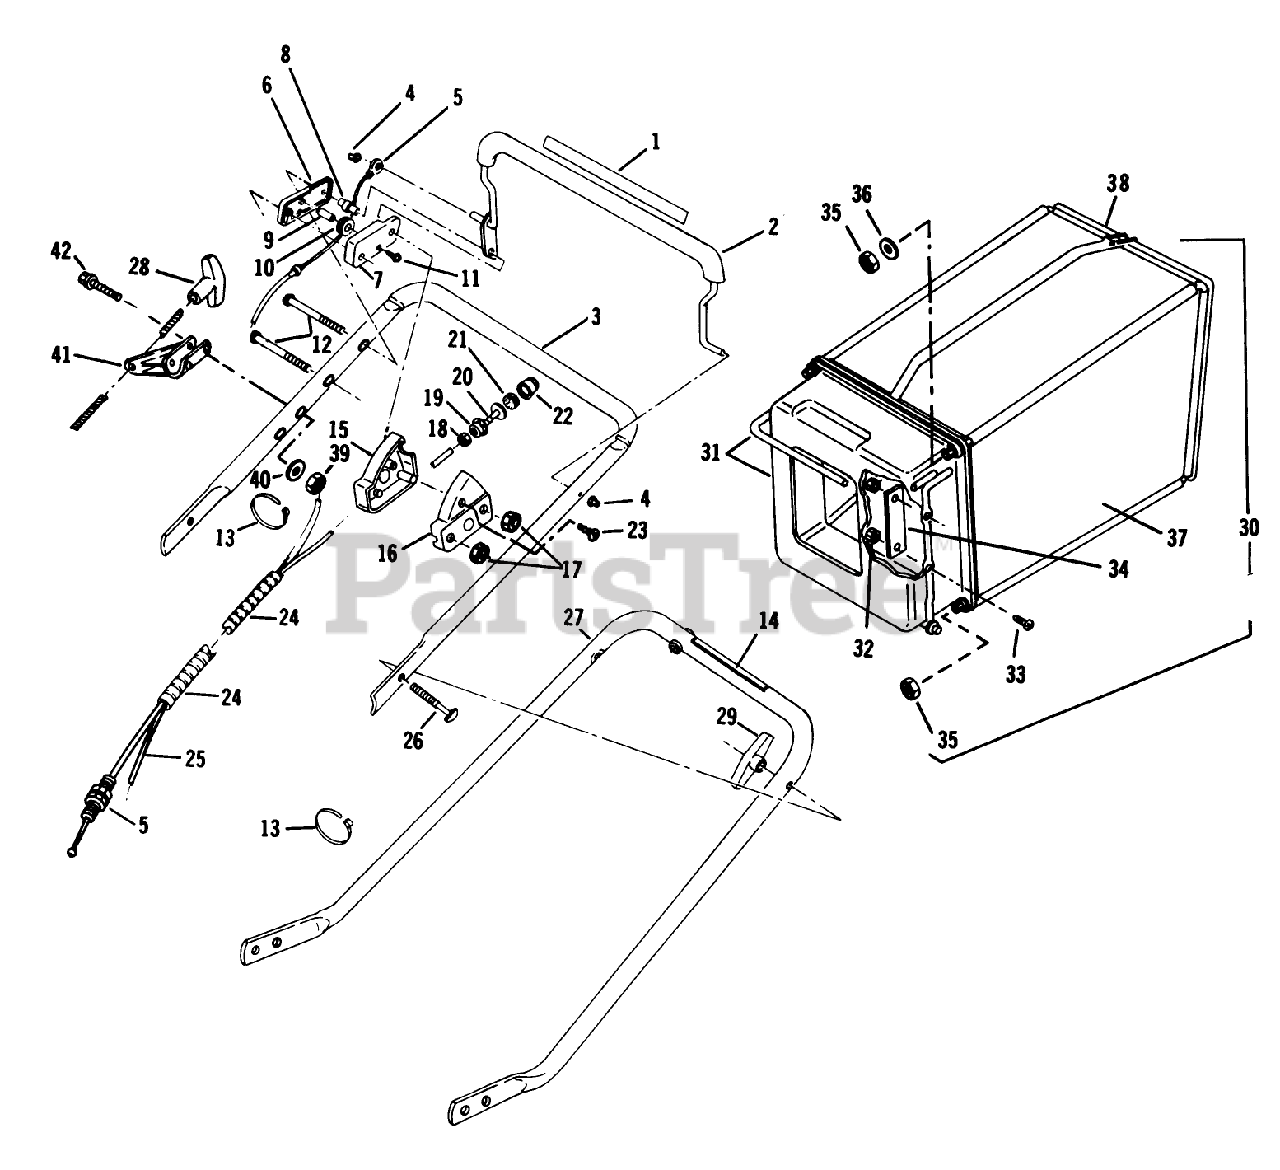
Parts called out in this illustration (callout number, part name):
5	CONTROL CABLE AY
8	COLUMN
9	PIN SKF
11	SCREW
17	NUT C/LOCK E
18	LOCKNUT S
21	FILTER S
23	SCREW LAWRENCE
25	PRIMER TUBING
26	BOLT QUALITY
28	HANDLE,STARTER
29	NUT-WING
30	Catcher Assembly-Complete
32	LOCKNUT E
35	LOCKNUT E
36	WASHER S
39	LOCKNUT E
40	WASHER
